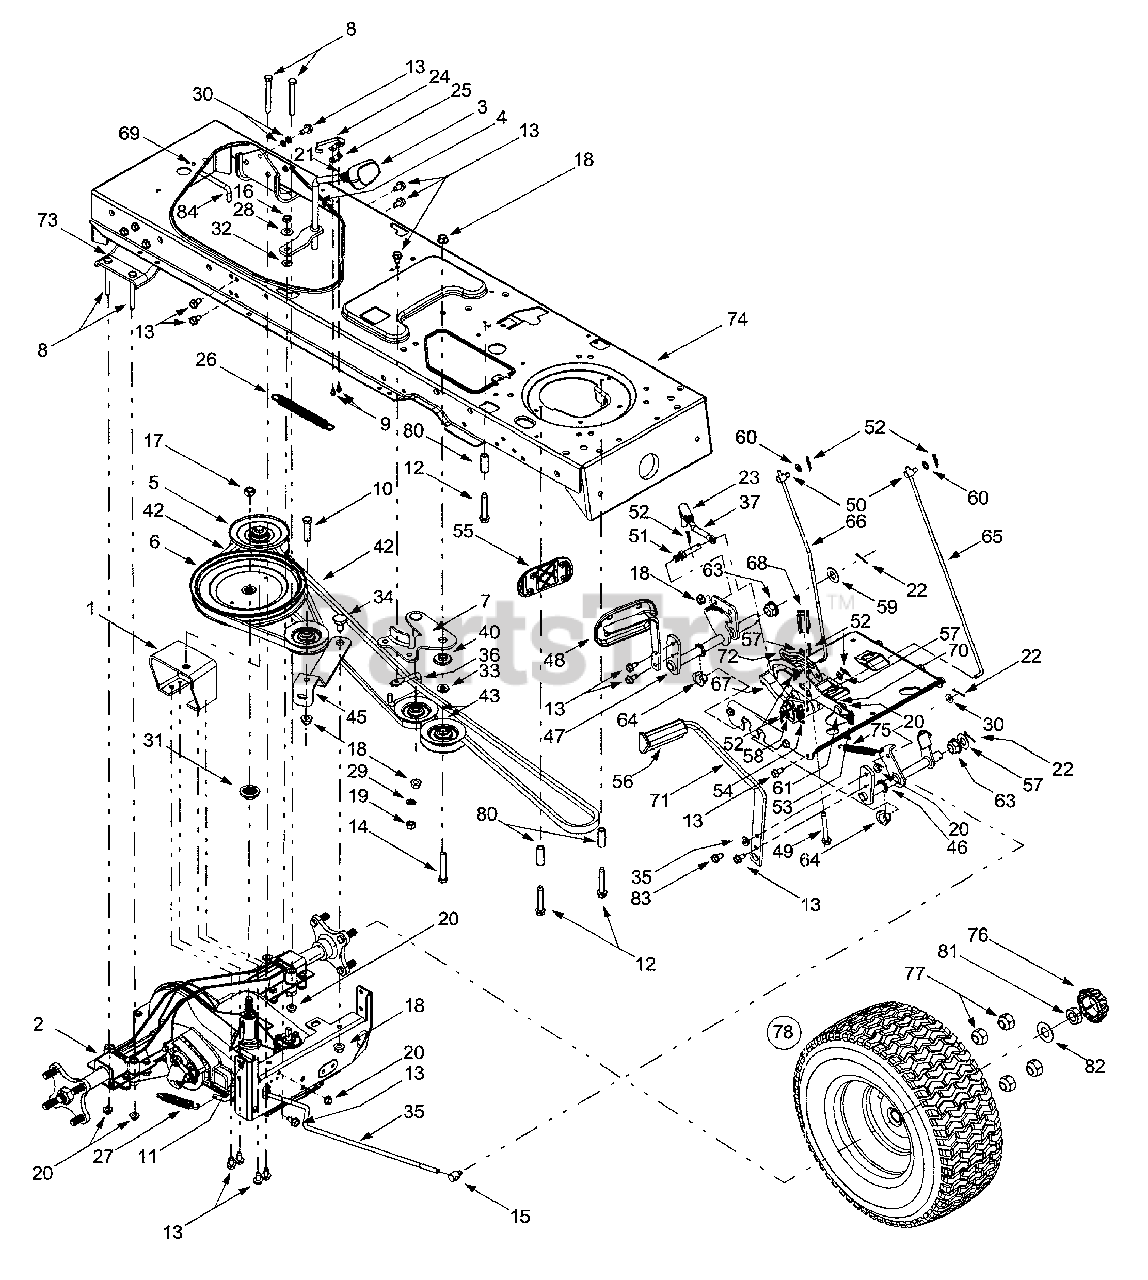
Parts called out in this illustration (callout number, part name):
1	Variable-speed Bracket Assembly
2	Two-speed Transmission Assembly
3	Shfter Knob
4	Shift Lever
5	Variable-speed Pulley Assembly
6	Transmission Pulley, 8.5
7	Double-idler Bracket
8	Hex Cap Screw, 5/16-18 x 3
9	Self Tapping Screw, #8-18 x.5
10	Hex Cap Screw, 3/8-16 x 1.75
11	Hex Cap Screw, 5/16-18 x 1.25
12	Self-tapping Screw, 1/4-20 x 1.25
13	Self Tapping Screw, 5/16-18 x .625
14	Hex Cap Screw, 3/8-16 x 2.25
15	Ferrule, 5/16 x .312 Dia.
16	Hex Jam Nut, 3/8-16
17	Hex Flange Nut, 7/16-20
18	Flange Lock Nut, 3/8-16
19	Hex Nut, 3/8-16
20	Flange Lock Nut, 5/16-18
21	Hex Jam Nut, 3/8-16
22	Cotter Pin
23	Ball Joint, 3/8-24
24	Spring Switch
25	Insulator Nut Plate
26	Extension Spring, .62 Dia. x 6.12
27	Extension Spring, .59 OD x 4.0
28	Bell Washer, .401 x .870 x .063
29	Lock Washer, 3/8
30	Flat Washer, 5/16
31	Pulley Hub, 1/2 Spline
32	Flat Washer, .44 x .75 x .06
33	Flat Washer, .407 x .812 x .135
34	Shoulder Screw, .625 Dia. x .21
35	Brake Rod
36	Belt Guard
37	Idler Adjustment Rod, 3/8
40	Shoulder Spacer, .380 ID
42	Drive Belt
43	Flat Idler, 2.75 OD
46	Brake Control Shaft Assembly
47	Speed Control Shaft Assembly
48	Drive Pedal Assembly
49	Self Tapping Screw, 5/16-18 x 2.5
50	Ferrule, 1/4-20
51	Pin, 3/8-16 x 2.43
52	Cotter Pin
53	Compression Spring, .34 OD x 1.0
54	Extension Spring, .5 OD x 1.41
55	Drive Pedal Pad
56	Brake Pedal Pad
57	Flat Washer, .281 x .5 x .0625
58	Flat Washer, 9/32 x 1/2 x 1/16
59	Flat Washer, .64 x 1.24 x .06
60	Flat Washer, .344 x .062 x .03
61	Shoulder Screw, .437 x 1.62
63	Hex Flange Bearing
64	Split Hex Flange Bearing
65	Cruise Control Rod
66	Brake Lock Control Rod
67	Cruise Latch
68	Spacer, 5/16 x 1.54
69	Self Tapping Screw, 1/4-20 x.5
70	Drive Lockout Bracket
76	Hub Cap
77	Lug Nut, 7/16-14
80	Spacer, .372 x .26 x 1.03
81	Jam Nut 3/4-16
82	Flat Washer, .78 x 1.59 x .06
83	Hex Screw, 5/16-18 x .75
84	Transmission Belt Guard Rod
